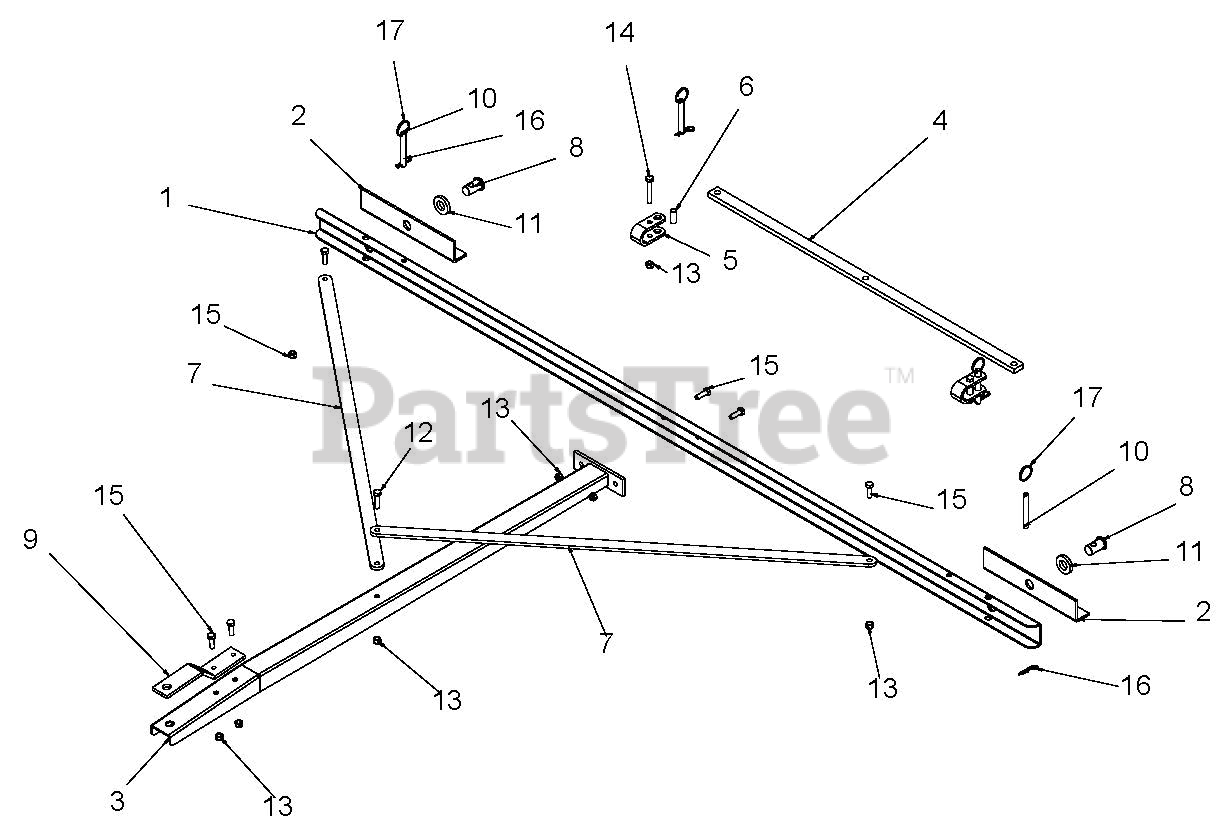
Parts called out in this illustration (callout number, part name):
1	Draw Bar
3	Tongue Weldment
6	Bushing, .437 OD x 1.00
8	Swivel Pin
10	Pin, Hitch
11	Washer, Flat Steel .812 x 1.5 x .135 YWZC
12	Bolt, 5/16-18 x 1.25 Grade 5
13	Nut, Nyloc 5/16-18
14	Bolt, 5/16-18 x 2 Grade 5
15	Bolt, 5/16-18 x 1 Grade 5
16	Pin, Hair
17	Ring, Retaining
